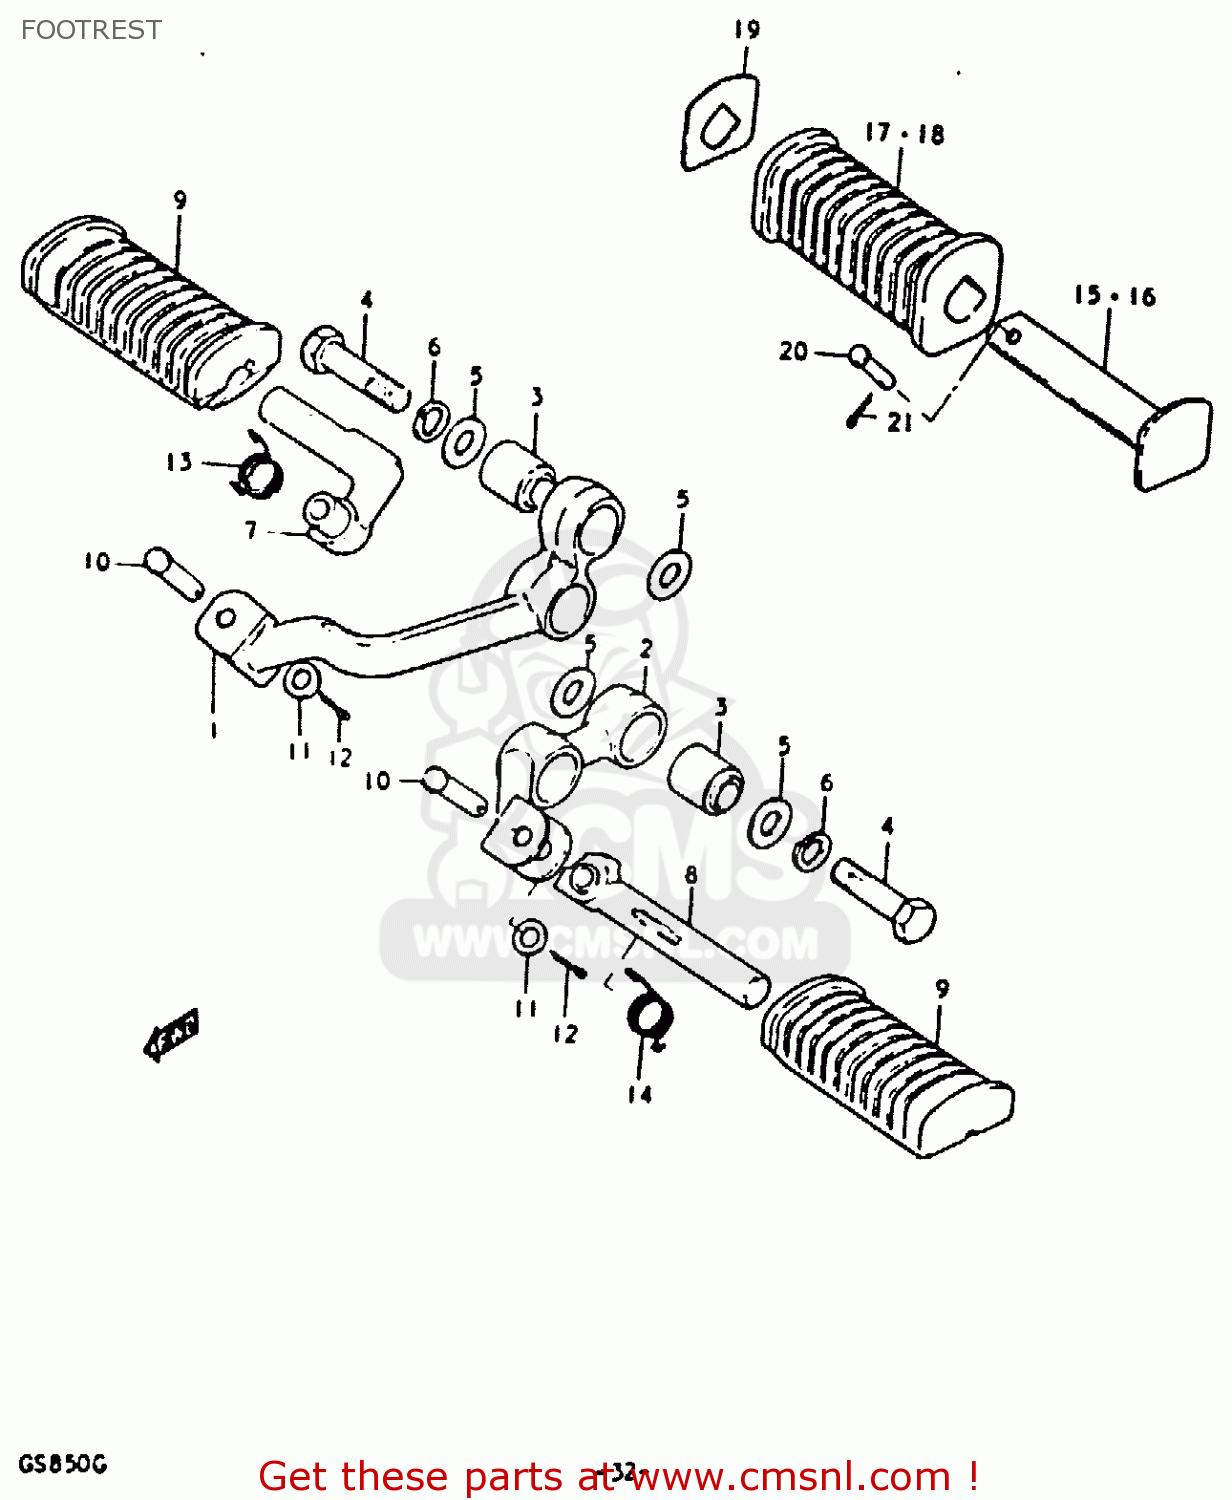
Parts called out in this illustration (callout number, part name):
1	BAR,FRONT FOOTREST
2	BAR,FRONT FOOTREST,LEFT
3	BUSH
4	BOLT
5	WASHER (10.1X21X2.3)
6	LOCK WASHER
7	BAR,FRONT FOOTREST,RIGHT NO
8	BAR,FRONT FOOTREST,LEFT NO
9	RUBBER,FR FOOTREST
10	PIN
11	WASHER
12	PIN 20X20
13	SPRING
14	SPRING
15	BAR,REAR FOOTREST
16	BAR,REAR FOOTREST
17	RUBBER,PILLION FOOTREST
18	RUBBER, LH
19	WASHER,REAR FOOTREST RUBBER
20	PIN
21	PIN
